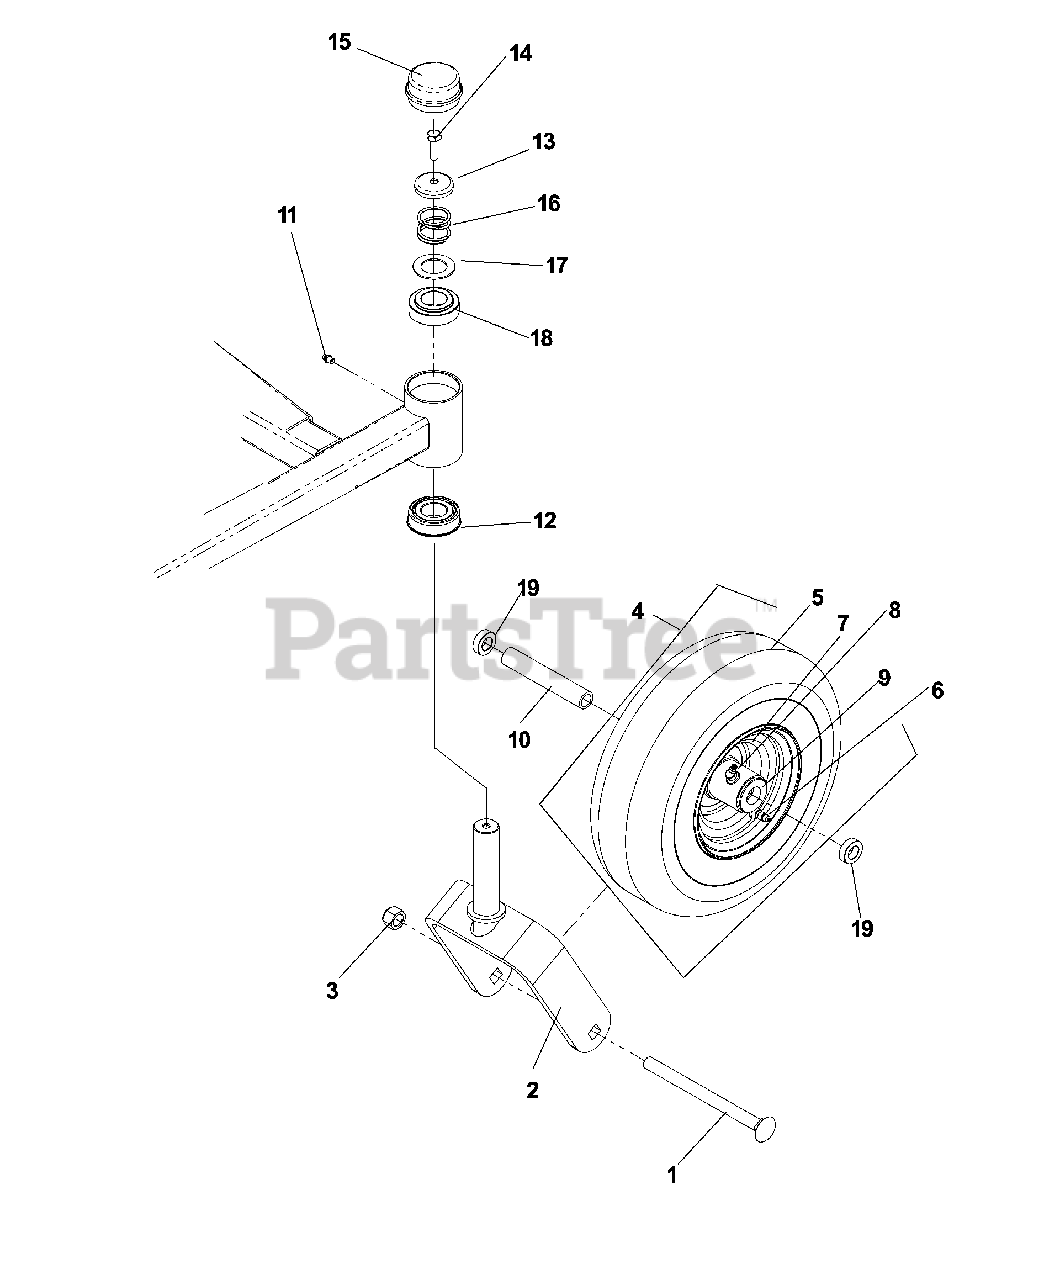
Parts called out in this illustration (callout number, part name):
1	RHSNB 1/2-13 X 6.50 GR2 ZD
2	CASTER DK BLUE
3	NUT 1/2-13 HEX NYLOC ZD
4	TIRE ASSEMBLY, BRG
5	TIRE.11"X4"-5.4PLY.SMOOTH.KEND
6	VALVE STEM TR-412
8	ZERK
9	BEARING RETAINER
11	ZERK, 3/16, DRIVE IN
12	BEARING FLANGED
13	CASTER.PLUG
14	HCS 5/16C X 1
15	DUST CAP
16	SPRING, CASTER
17	WASHER, 1.025 ID X 1.64
18	BUSHING, CASTER
19	SPACER, 5/16"
